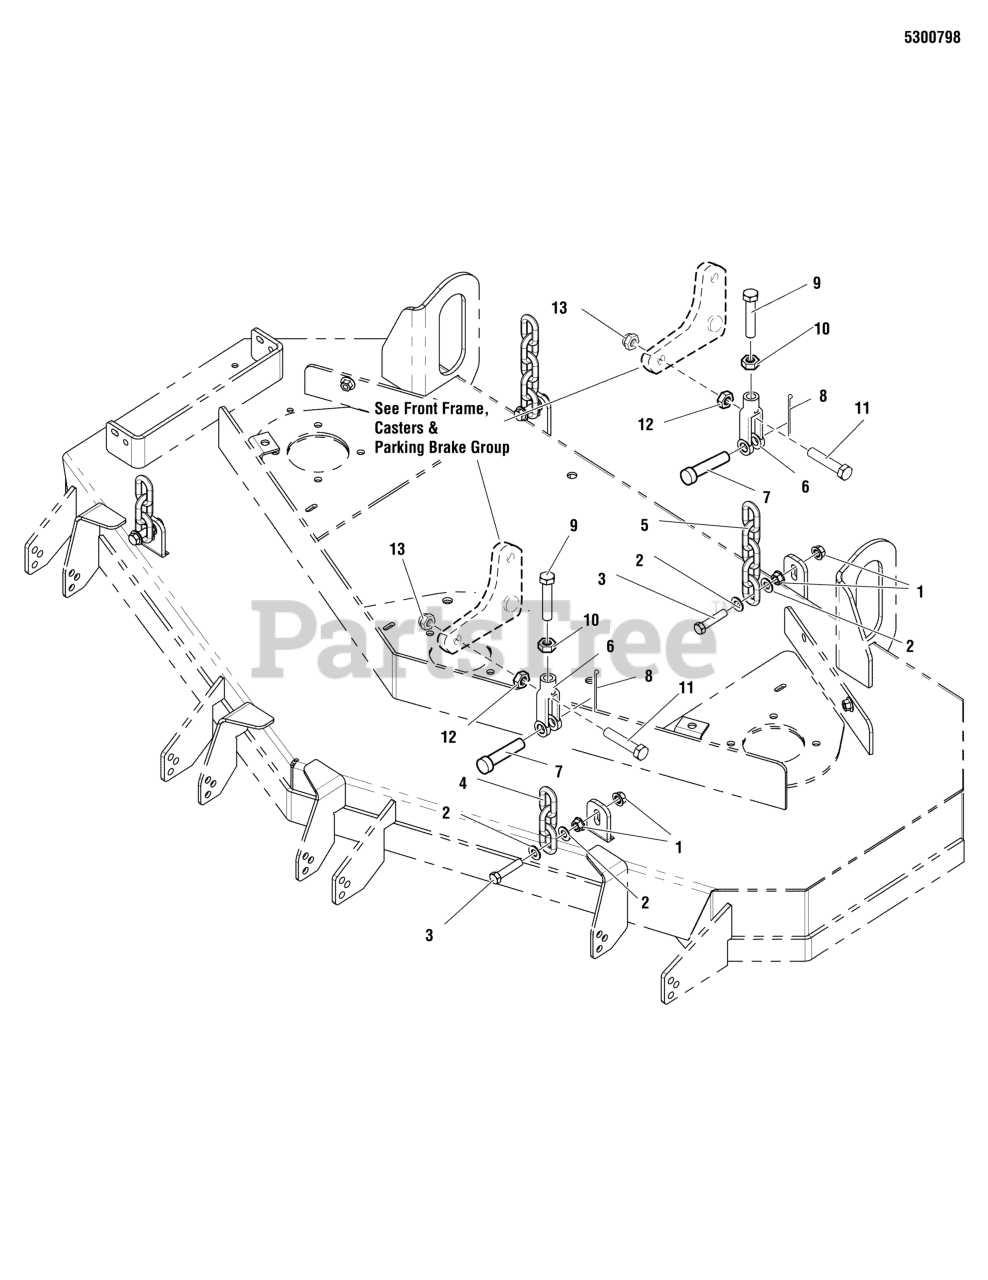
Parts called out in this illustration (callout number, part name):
1	NUT, 3/8-16 HEX LG. SERR FLG
2	WASHER, 3/8 SAE
3	BOLT, 3/8-16 X 1-3/4" GD5 CZ
4	CHAIN, 5/16" GD30, 3 LINKS
5	CHAIN, 5/16" GD30, 5 LINKS
6	CLEVIS, 5/16-18, 3/8" PIN HOLE
7	PIN, CLEVIS, 3/8" X 1-1/8"
8	PIN, COTTER, 1/8 X 1-1/4
9	BOLT, 5/16-18 X 2" GD5 TFL
10	NUT, 5/16-18 HEX JAM
11	BOLT, 3/8-16 X 2, GD5, CZ
12	NUT, 3/8-16 HEX JAM
13	NUT, 3/8-16 HEX NYLOCK FLANGE
